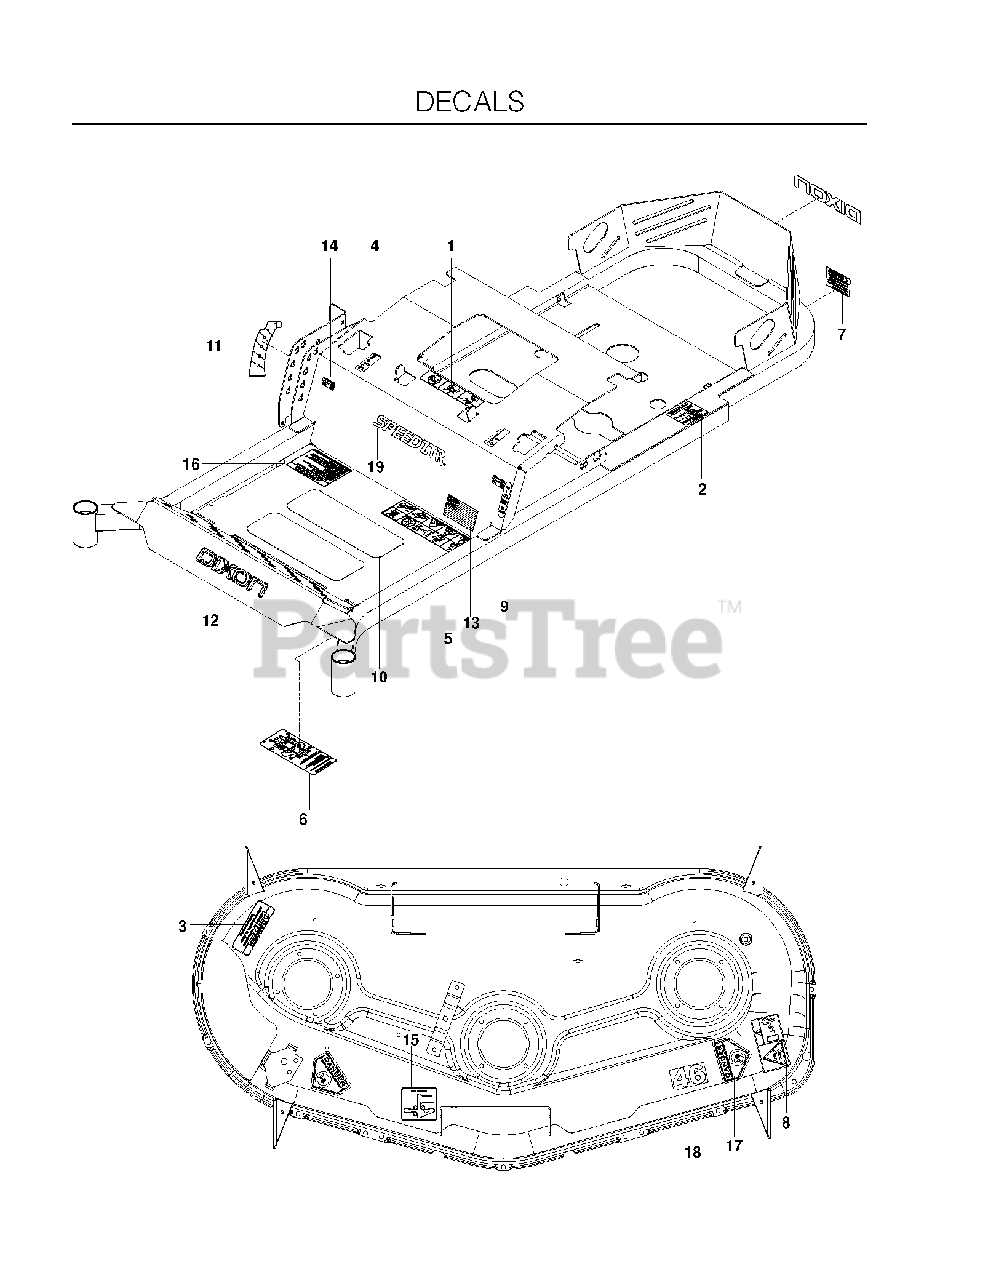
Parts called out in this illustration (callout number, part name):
1	DECAL, BATTERY
2	DECAL, DO NOT MOUNT
3	DECAL, DANGER
4	DECAL, MOTION CONTROL
5	DECAL, SAFETY WARNING
6	DECAL, SERVICE
7	DECAL, PROP. 65
8	DECAL, EURO SEVERING
9	DECAL, PARK BRAKE
10	ANTI-SKID PAD
11	DECAL, HEIGHT
12	DECAL, DIXON LOGO, DOMED
13	DECAL, FLAG
14	DECAL, F.S.T.
15	DECAL, BELT ROUTING
16	DECAL, WARNING
17	DECAL, CPSC
18	DECAL, 46"
19	DECAL, SPEEDZTR, 8"
